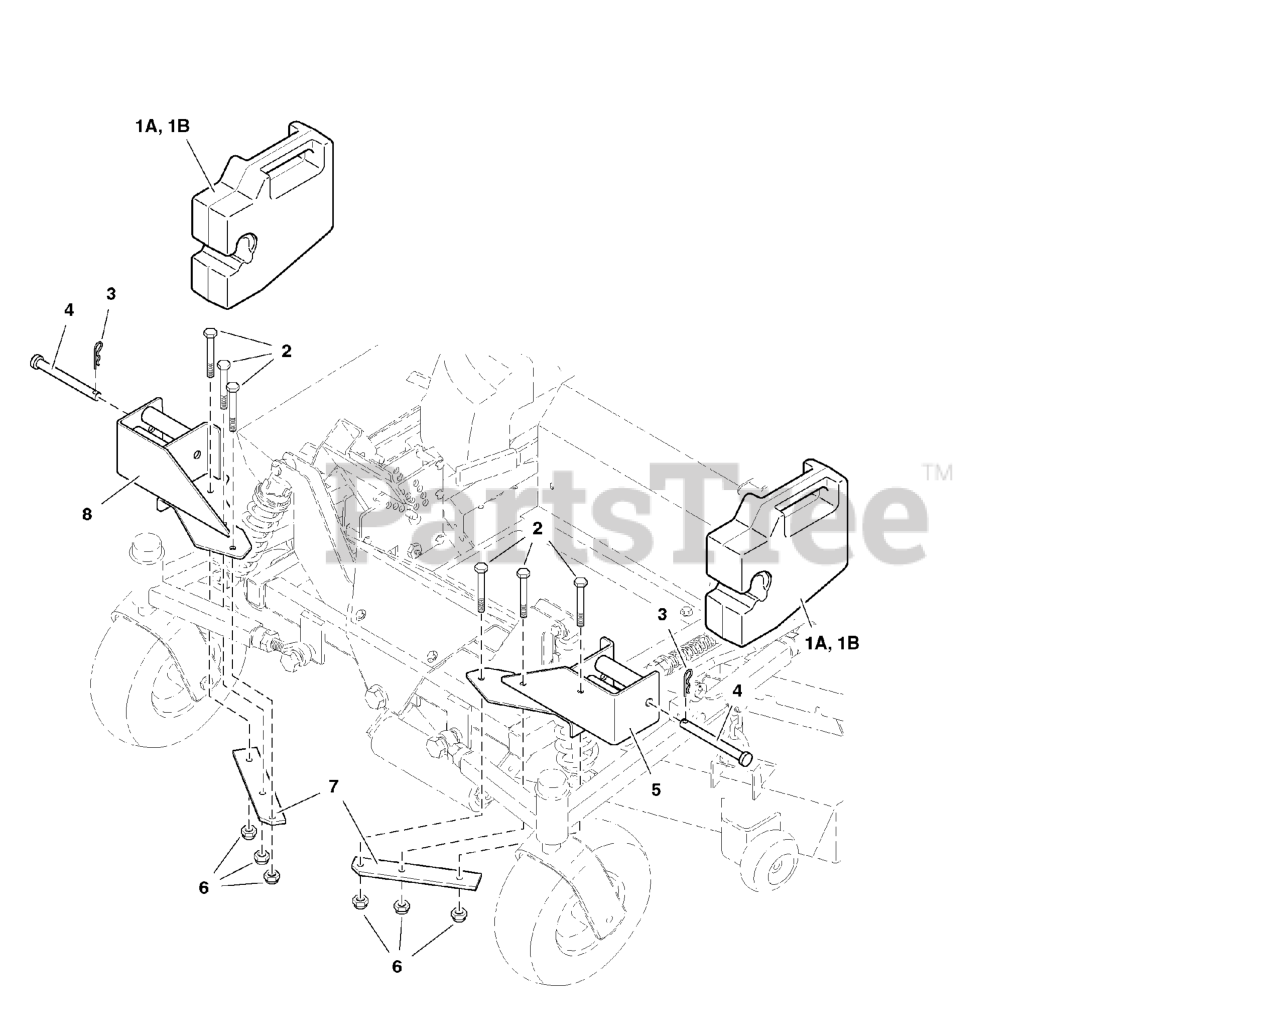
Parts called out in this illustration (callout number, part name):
1A	WEIGHT, 30 lbs.
1B	WEIGHT, 50 lbs.
2	BOLT, 5/16-18 x 2-1/2
3	HAIRPIN CLIP
4	CLEVIS PIN, 1/2 x 4-1/2
5	WEIGHT MOUNT-LH
6	NUT, 5/16-18 Hex Nylon Lock
7	BAR CLAMP
8	WEIGHT MOUNT-RH
